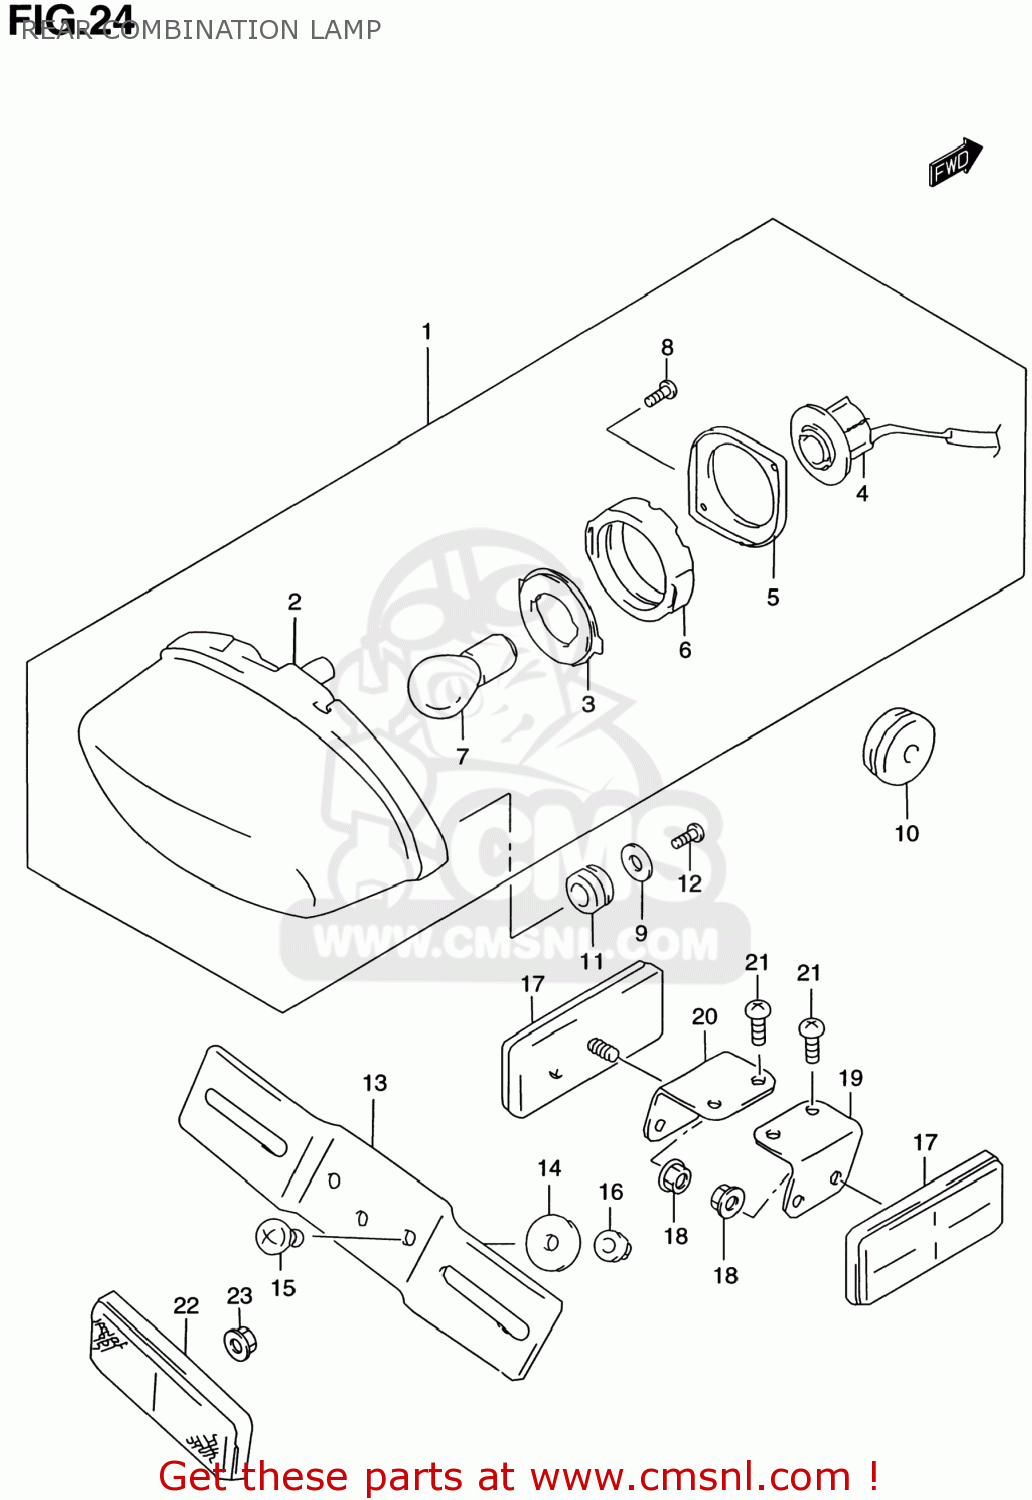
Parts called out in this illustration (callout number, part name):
1	LAMP ASSY,RR COMBINATION
2	LAMP UNIT
3	PLATE NO.1
4	SOCKET & CORD
5	PLATE NO.2
6	CUSHION
7	BULB(12V21/5W)
8	SCREW
9	WASHER(5.5X20X1.2)
10	GROMMET
11	CUSHION
12	SCREW
13	BRACKET,LICENSE PLATE
14	WASHER(6.5X20X1.6)
15	SCREW 6X12
16	NUT
17	REFLECTOR ASSEMBLY,REAR
18	NUT
19	BRACKET,RR SIDE RR,L
20	BRACKET,RR SIDE RR,R
21	SCREW 6X12
22	REFLECTOR ASSEMBLY,REAR
23	NUT
